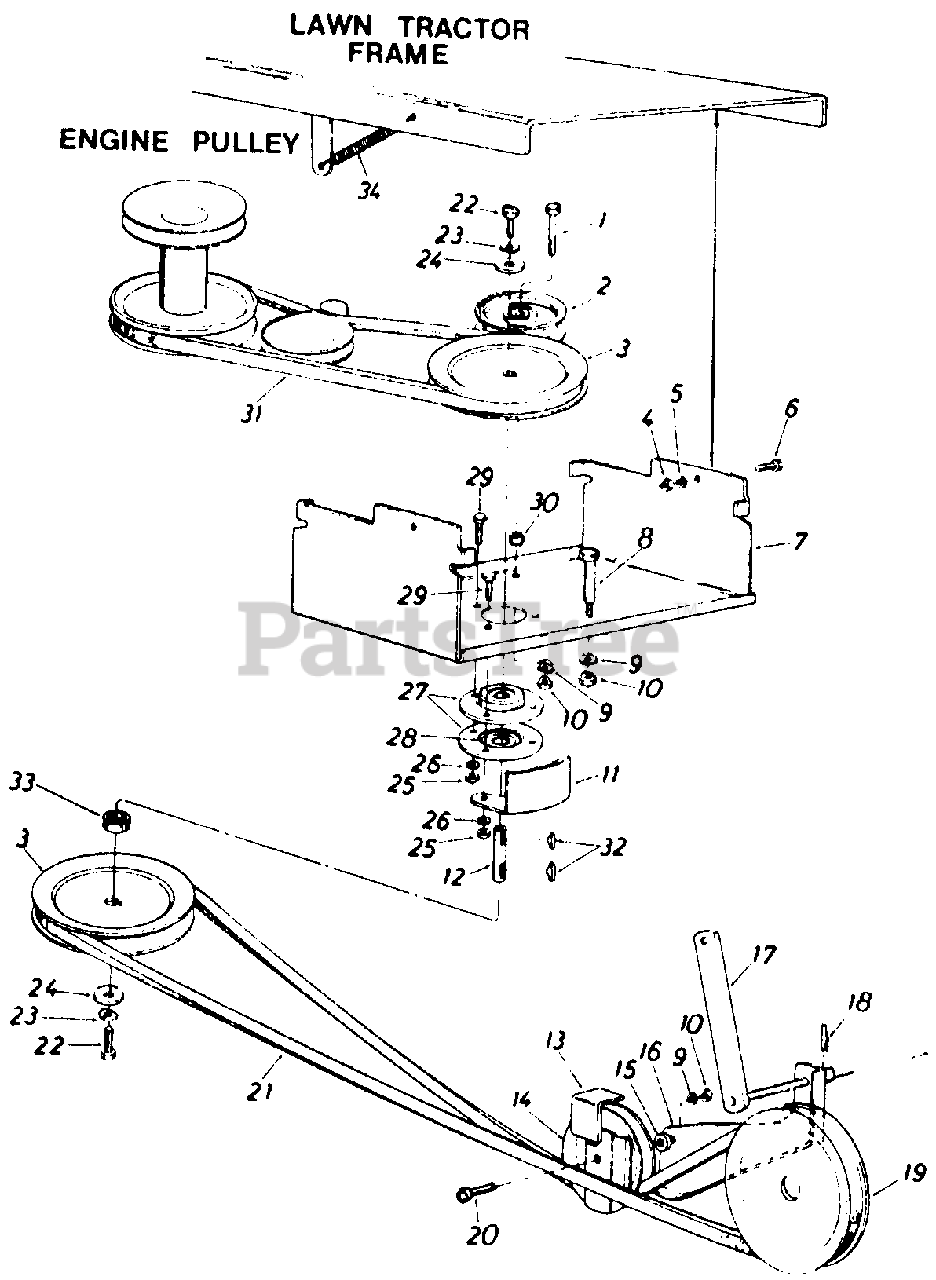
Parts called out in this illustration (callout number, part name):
1	Hex Bolt 3/8-16 x 2.00" Lg.*
2	Fl.-Idler w/Flanges 3-3/4" O.D.
3	5/8" "V"-Pulley.790" I.D. x .650" O.D.
4	Hex Nut 3/8-24 Thd.*
5	L.-Wash. 3/8" I.D. Heavy Duty
6	Hex Bolt 3/8-24 x .88" 4.*
9	L.-Wash. 3/8" I.D.*
10	Hex Nut 3/8-16 Thd.*
13	Belt Separator Plate
14	Fl.-Idler w/Flanges 3.25"
15	Fl.-Wash. .406" I.D. x 1.25"
18	Spring Pin Roil 3/16" Dia.
19	5/8" V-pulley 1.50" I.D. x 6.50" O.D.
20	Hex Bolt 3/8-16 x 1.75" Lg.*
21	"V"-Belt
22	Hex Bolt 5/16-18 x .88" 4. Spec.
23	L.-Wash 5/16" I.D.*
24	Fl.-Wash. .344" I.D. x 1.125"
25	Hex Nut 5/16-18 Thd.*
26	L.-Wash. 5/16" I.D.*
27	Bearing Housing 1.85" I.D.
28	Ball Bearing 1.85" O.D.
29	Hex Sems Bolt 5/16-18 x .75"
30	Spacer
31	Belt 1/2" Wide x 52" Long
32	Hi-Pro Key 3/16" x 5/8"
33	Spacer.66" I.D. x 1.0" O.D.
34	Extension Spring
